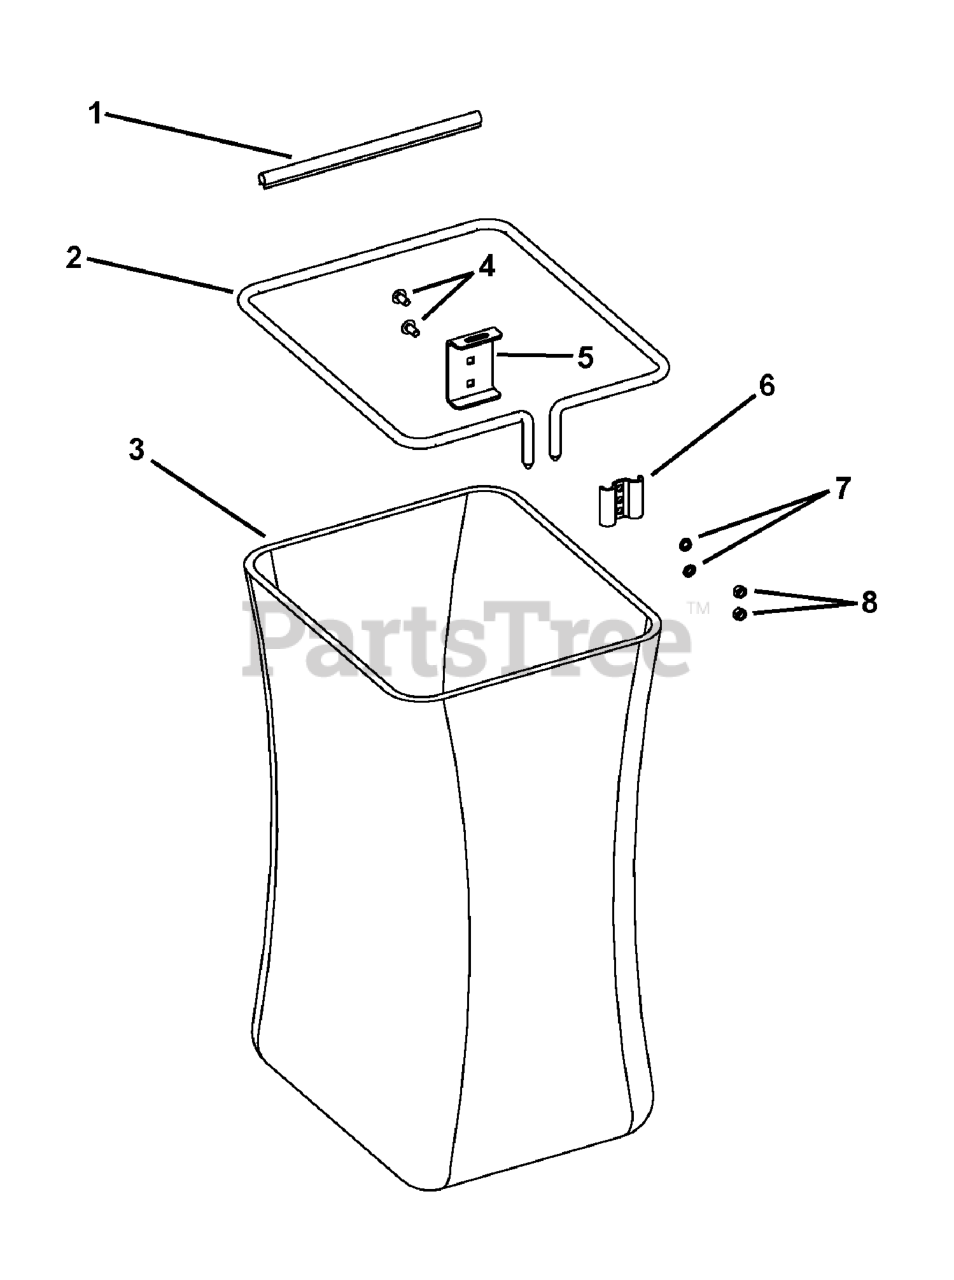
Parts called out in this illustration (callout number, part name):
1	TUBE, CLIP, GRASS BAG
2	HOOP, BAG TRIPLE
3	BAG, GRASS CATCHER, CLOTH
4	BOLT, CARRIAGE, 5/16-18 X 3/4
5	HANGER, GRASS BAG
6	CLAMP, GRASS BAG
7	LOCKWASHER, SPRING 5/16
8	NUT, HEX 5/16-18 NC-2B
